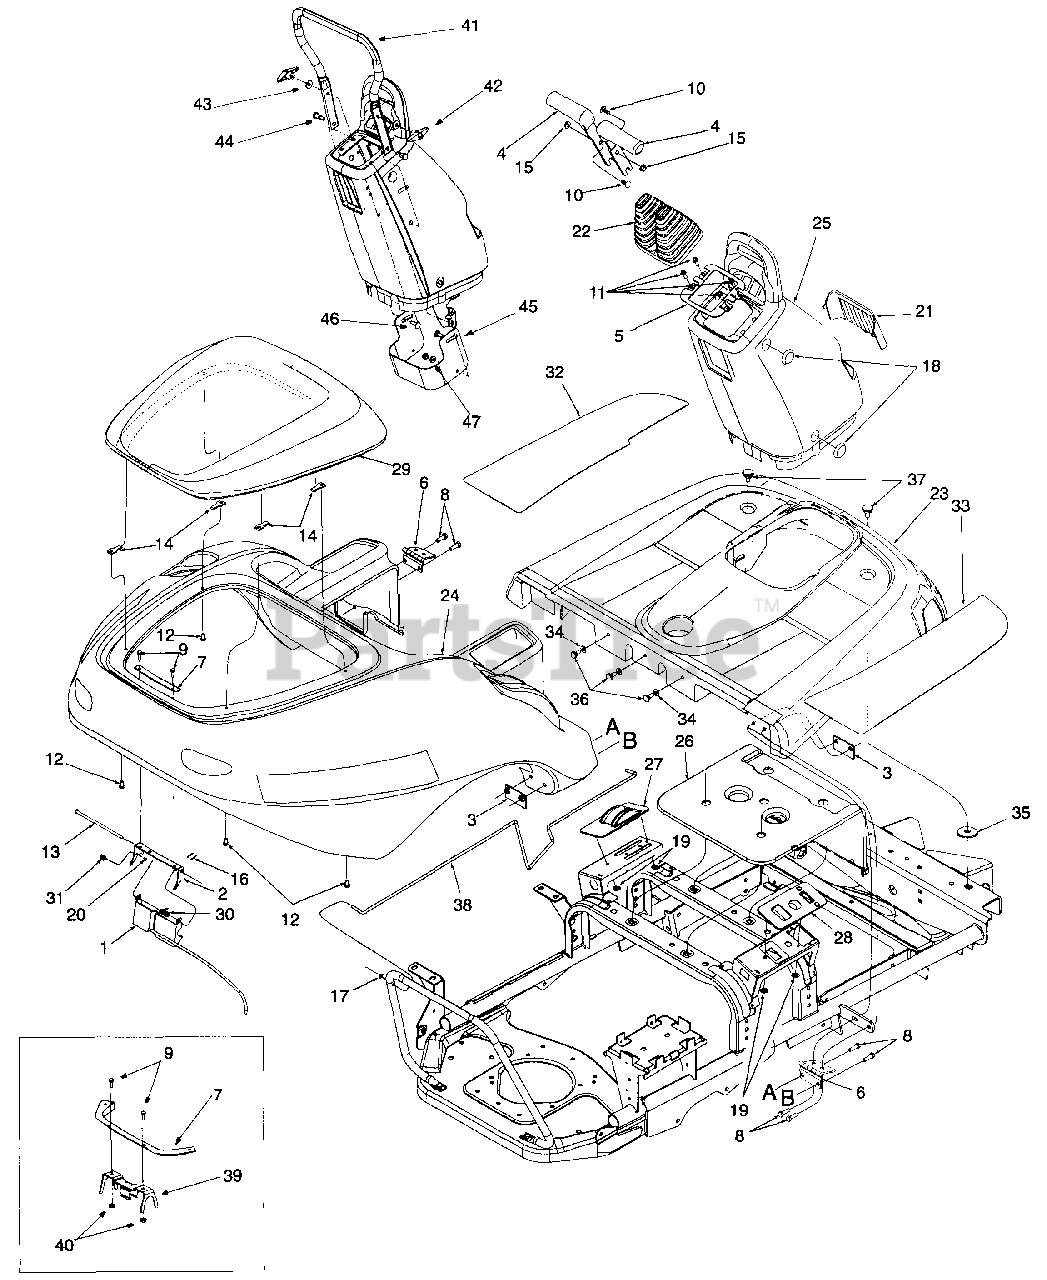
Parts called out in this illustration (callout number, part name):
1	Handle Ass'y, Latch
2	Bracket, Latch
3	Plate Ass'y, Body Mounting
4	Handle, Control
7	Plate, Latch Mounting
8	Screw, Hex Cap, 5/16-18 x 1.0 GR5
9	Screw, Pan Hd, #10-24 x .625
10	Bolt, Carriage, 5/16-18 x .75
11	Screw, Hex Wash. Hd. Tap 1/4-20 x .75
12	Screw, Truss Machine 1/4-20 x .625 GR2
13	Rod, Latch Mounting
14	Nut, U-Type Speed, 1/4-20
15	Nut, Hex Flange Lock, 5/16-18 GR5
16	Pin, Cotter, 1/16 x .75
17	Push Cap, 1/4
18	Plug, Button
19	Push Nut
20	Rivet, Pop, .125 Dia
21	Lens, Headlight
22	Bellow, Control
23	Body, Front Floor
24	Body, Rear Engine Compartment
26	Cover, Seat Base
27	Cover, LH Control Panel
28	Cover, RH Control Panel
29	Cover, Engine
30	Spring, Torsion
31	Clip, Spring
32	Pad, Floor LH
33	Pad, Floor RH
34	Washer, Flat
35	Washer, Flat, .406 x 1.5 x .110
36	Bolt, Shoulder
37	Bolt, Shoulder, .75 x .245:3/8-16
38	Rod, Prop Support
39	Clip Spring Bracket Assembly
40	Hex Nut Lock Flange 1/4-20
43	Bell Wash .340 ID
44	Shoulder Screw .437 Dia .54
47	Nut, Hex Flange Lock, 5/16-18 GR5
